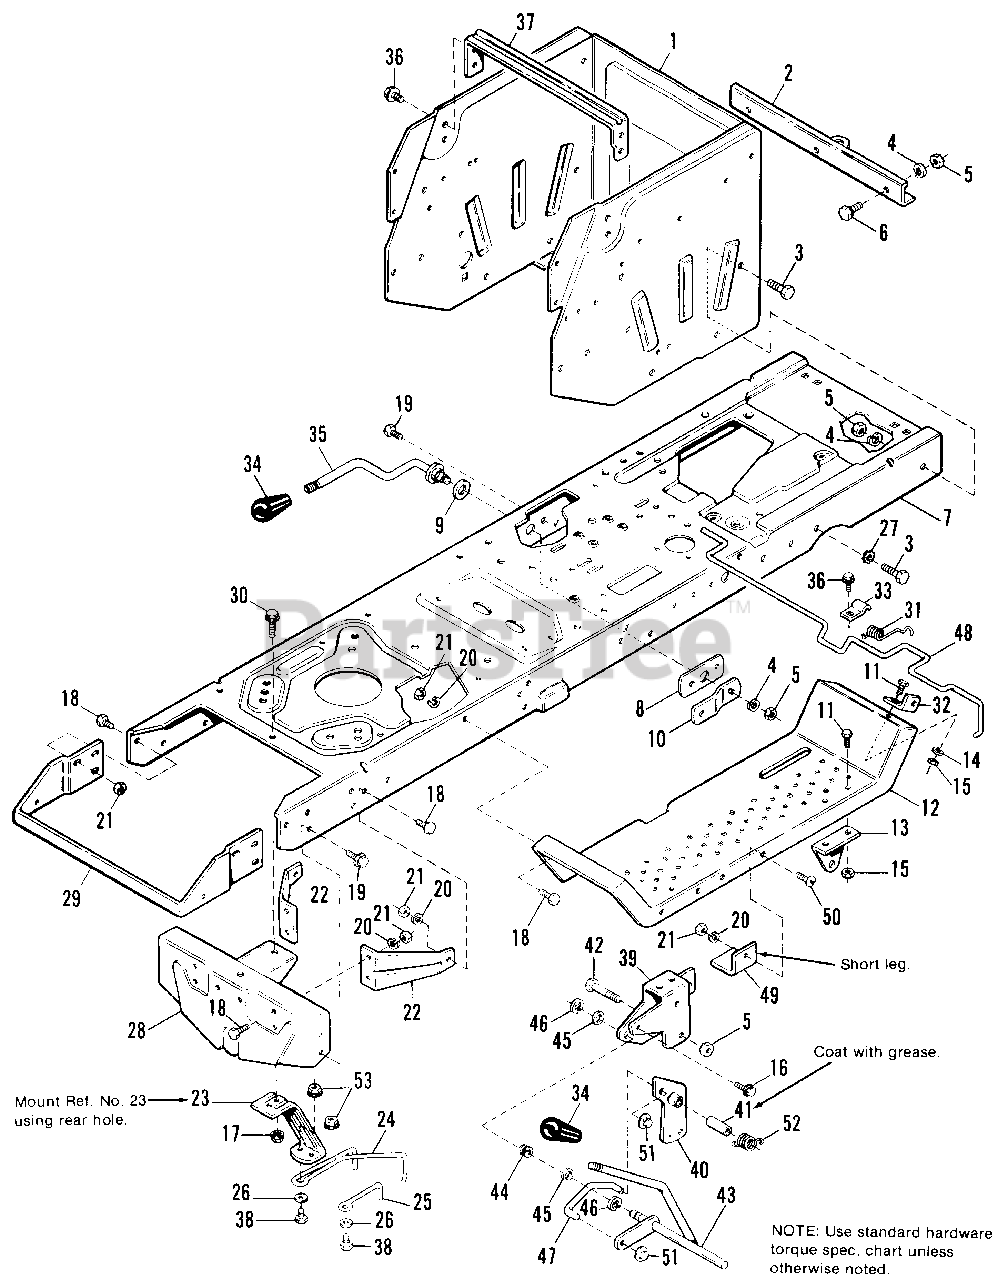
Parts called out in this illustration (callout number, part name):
1	SUPPORT, Axle, Wrapper
2	BAR, Draw
3	CAPSCREW Hex Hd., 3/8-16 x 1
4	LOCKWASHER, 3/8
5	NUT, Hex, Full, 3/8-16
6	CAPSCREW, Hex Hd., 3/8-16 x 3/4
8	BAR, Support
9	WASHER, Nylon
10	ARM, Support
11	CAPSCREW, Hex Hd., 1/4-20 x 5/8
13	SUPPORT, Clutch
14	LOCKWASHER, 1/4
15	NUT, Hex, Full 1/4-20
16	SCREW, Taptite, 1/4-20 x 1/2
17	NUT, Flange, Whizlock, 5/16-18
18	CAPSCREW, Hex Hd., 5/16-18 x 3/4
19	SCREW, Hex, Taptite, 5/16-18 x 3/4
20	LOCKWASHER, 5/16
21	NUT, Hex, Full, 5/16-18
22	BRACE, Axle Support
26	WASHER, Plain, 1/4
27	LOCKWASHER, Ext. Tooth, 3/8
28	SUPPORT, Axle
29	SUPPORT, Hood
30	SCREW, Hex Flange Hd., 5/16-18 x 1-1/4
31	SPRING, Torsion
32	BRACKET, Seat Latch
34	KNOB
35	HANDLE, Lift
36	SCREW, Hex, Wash. Hd., Taptite, 5/16-18 x 1/2
37	BRACE, Seat
38	CAPSCREW, Taptite, 5/16-18 x 7/8
39	BRACKET, P.T.O.
40	ARM ASSY, P.T.O. Rod
42	CAPSCREW, Hex Hd., 3/8-16 x 2-1/4
43	HANDLE ASSY, P T.O.
46	RING, Snap
47	LINK, P.T.O.
48	ROD, Latch, Seat
49	UP-STOP, Mower
50	SCREW, Truss Hd., Slotted, 5/16-18 x 3/4
51	PAL NUT, 3/8
53	NUT, Lock, Hex, Fl., 5/16-18
